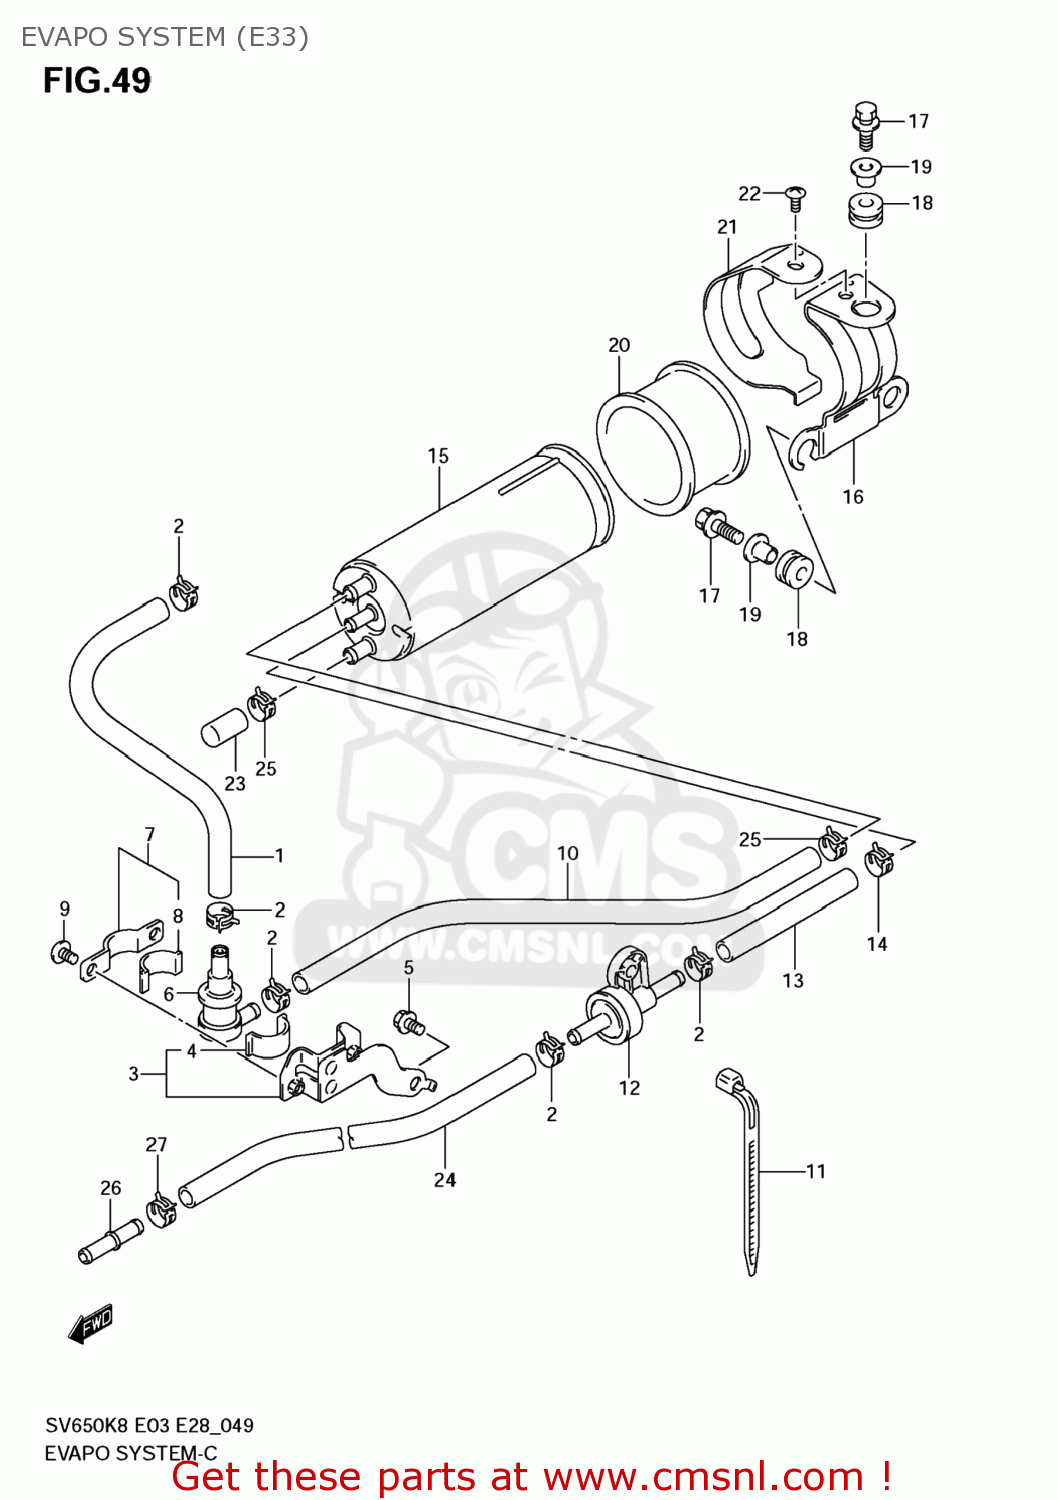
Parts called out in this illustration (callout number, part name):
1	HOSE,TANK & BREATHER VALVE
2	CLIP
3	PLATE,BREATHER VALVE
4	CUSHION
5	BOLT
6	VALVE,FUEL TANK BREATHER
7	PLATE,FUEL TANK BREATHER NO.2
8	CUSHION
9	SCREW
10	HOSE,BRTHR VALVE & 2 WAY VALVE
11	CLAMP(L:165)
12	VALVE,2 WAY & BREATHER VALVE
13	HOSE,2 WAY VALVE & CSTR
14	CLIP
15	CANISTER ASSY,CHARCOAL
16	BRACKET,CANISTER
17	BOLT(6X25)
18	CUSHION
19	WASHER
20	CUSHION,CANISTER
21	HOLDER,CANISTER
22	SCREW
23	CAP,OD:11.5
24	HOSE
25	CLIP
26	JOINT
27	CLIP
